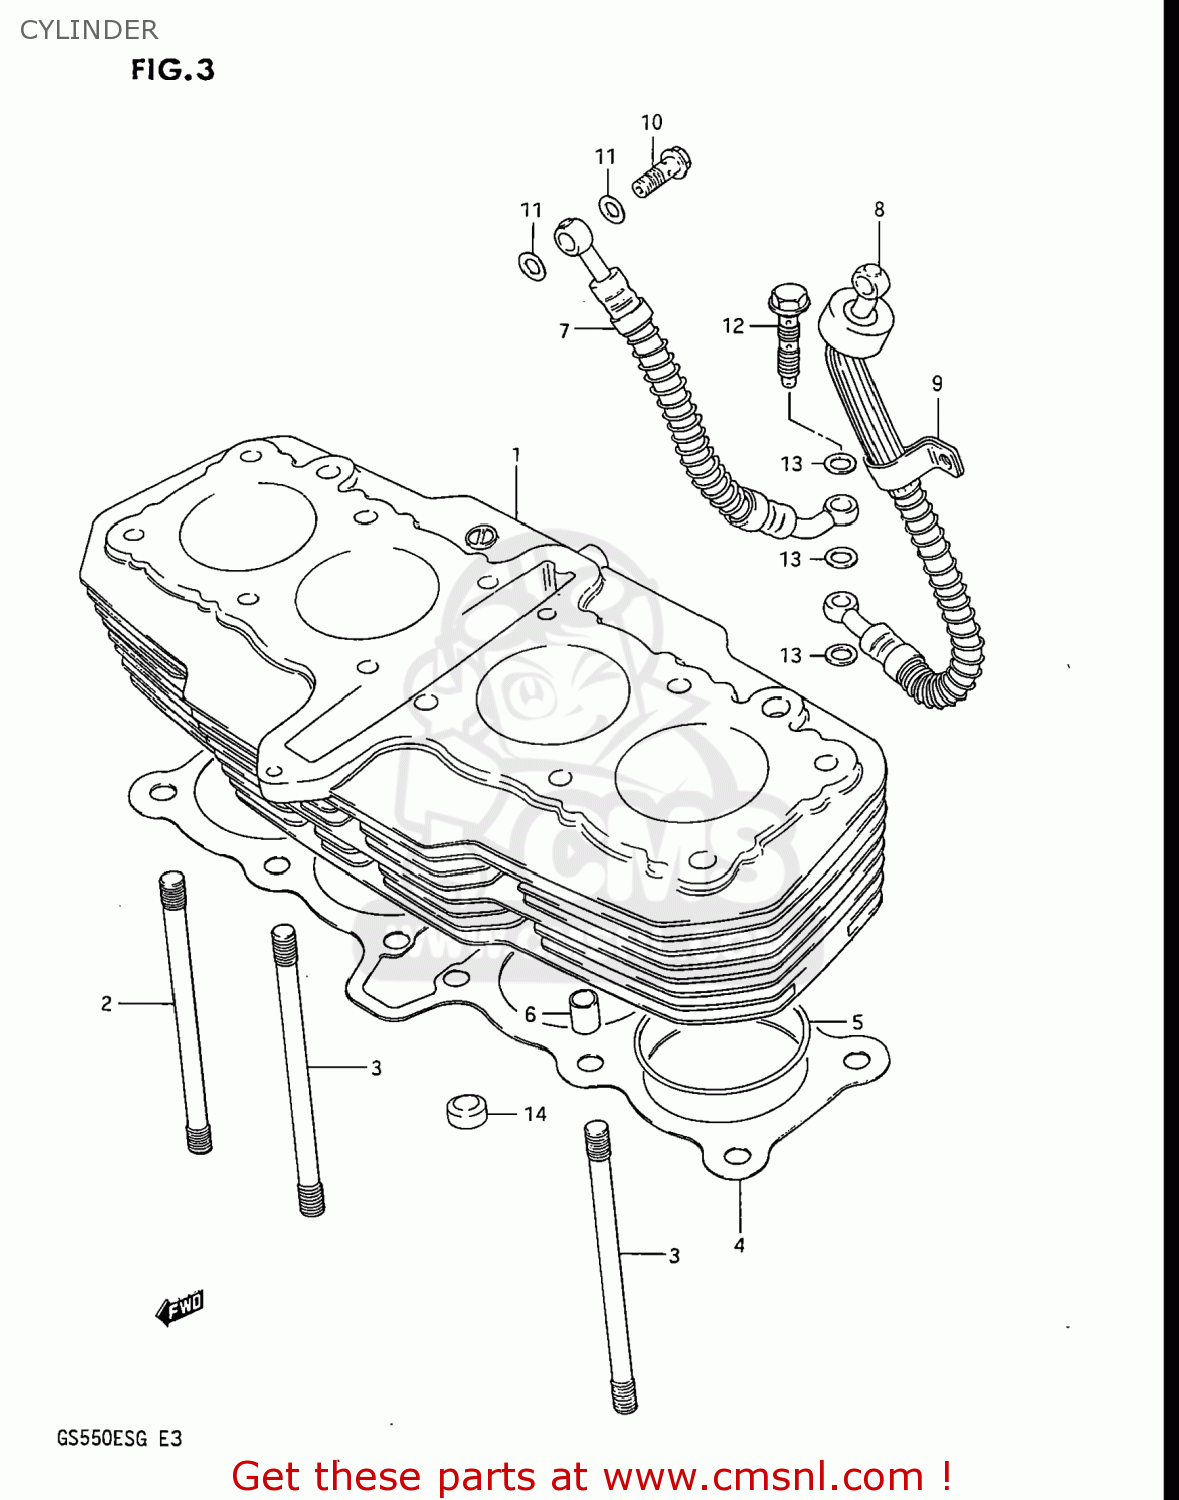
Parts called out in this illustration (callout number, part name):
1	CYLINDER
2	STUD
3	BOLT,STUD
4	GASKET,CYLINDER (MCA)
5	O RING(D:2,ID:61)
6	PIN
7	HOSE,OIL CRANKCASE,R
8	HOSE,OIL CRANKCASE,L
9	CLAMP,OIL HOSE CRANKCASE
10	BOLT UNION
11	GASKET 8.2X14X1 (NAS)
12	BOLT,OIL PIPE
13	WASHER(10X15X1.5)
14	PAD,CYLINDER HEAD
